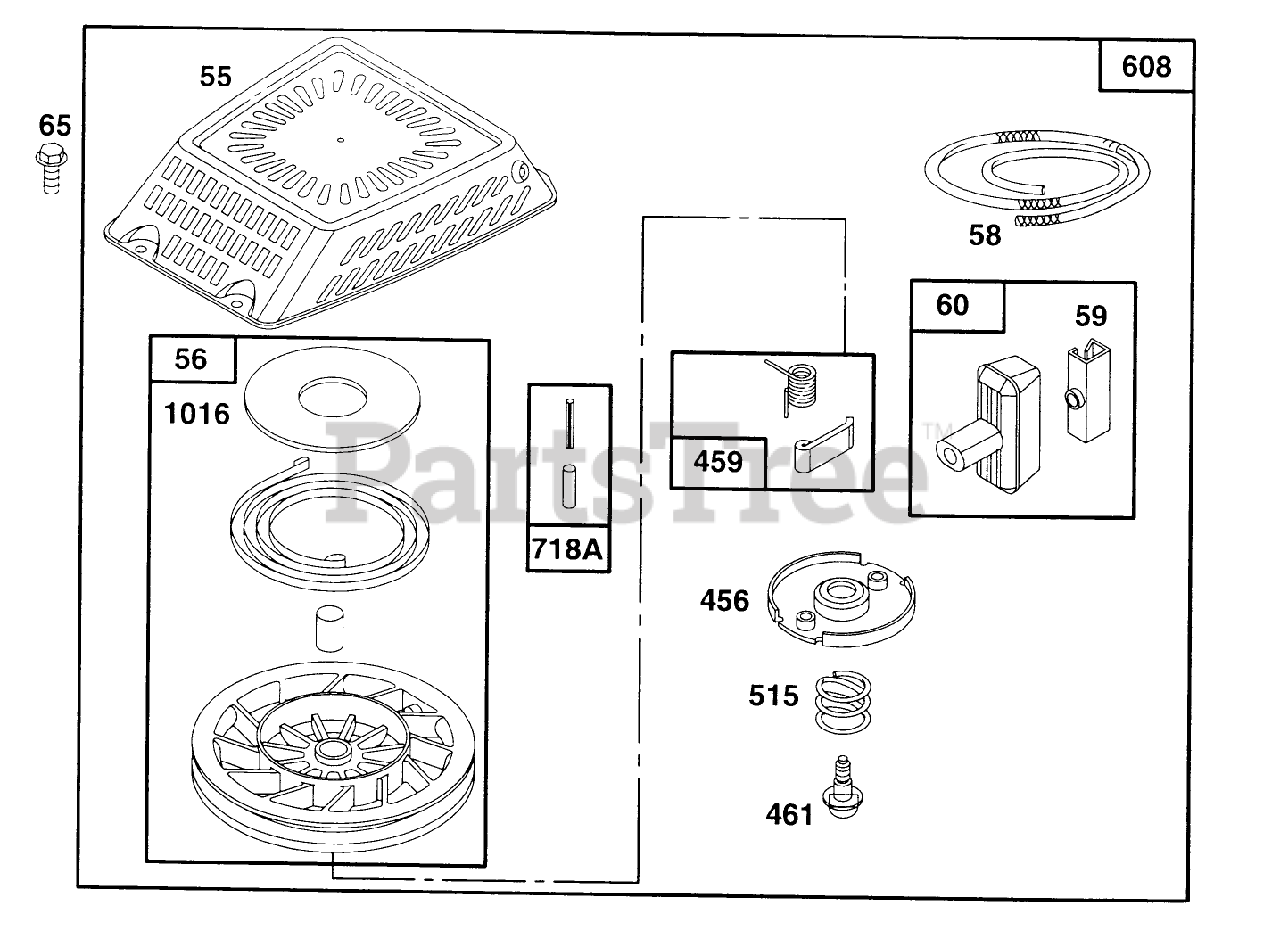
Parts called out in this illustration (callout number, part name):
59	INSERT-HANDLE, REWIND
456	RETAINER - SPRING
515	SPRING - RETAINER
